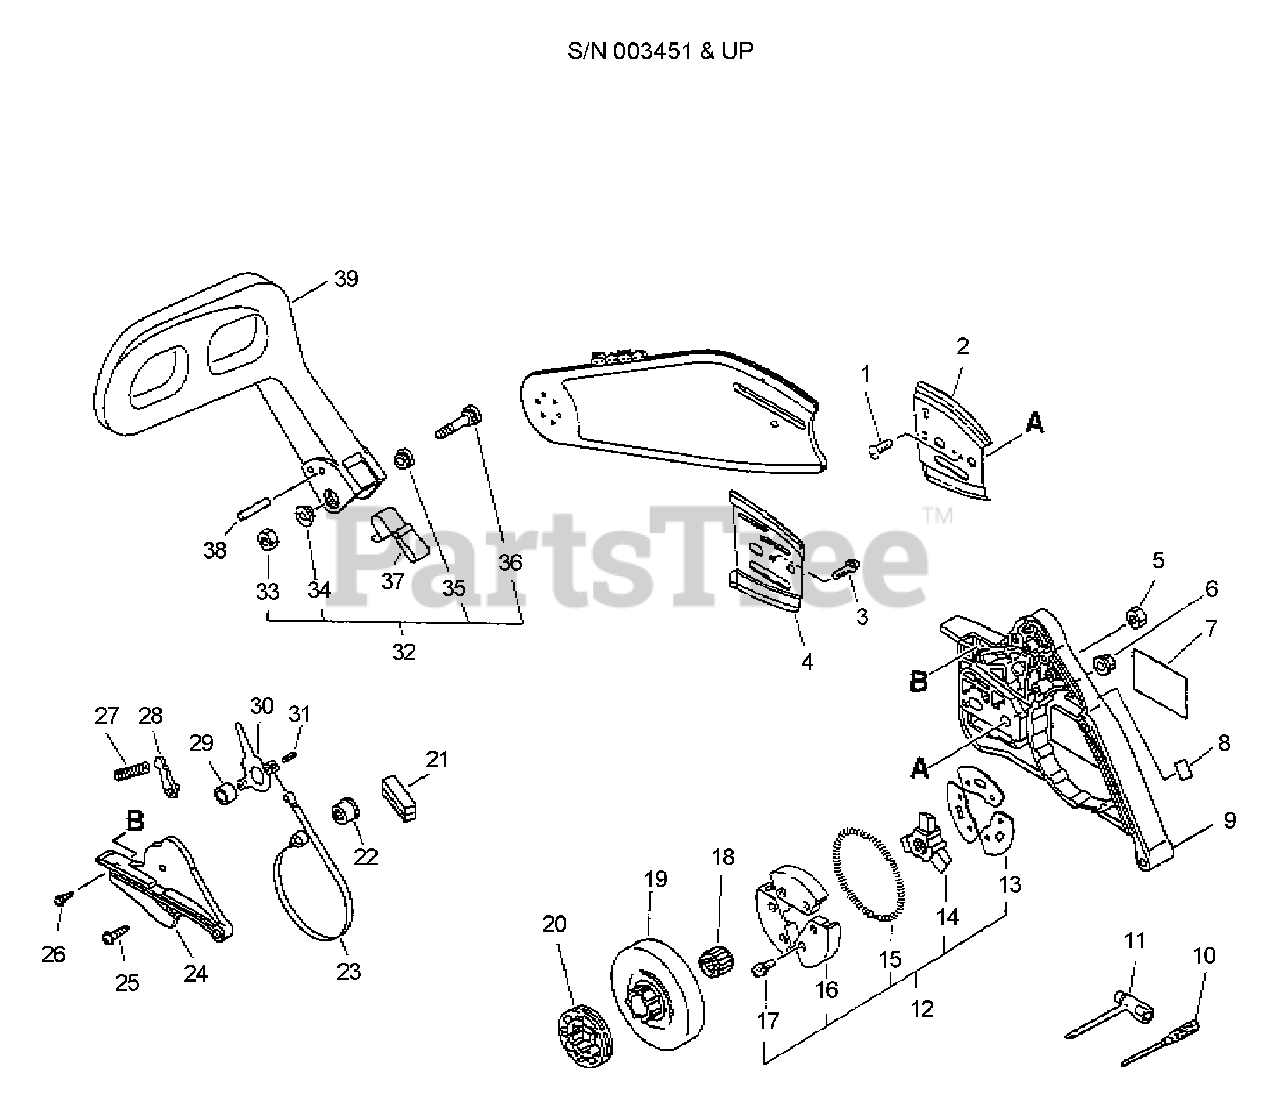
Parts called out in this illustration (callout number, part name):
1	SCREW - 3X6
2	PLATE, GUIDE - OUTER
3	SCREW - 4X8
4	PLATE, GUIDE - INNER
6	NUT - FLANGE
7	LABEL - ECHO
8	LABEL - CAUTION
9	GUARD, SPROCKET
10	SCREWDRIVER
11	T-WRENCH - 13X19mm
12	CLUTCH ASSY
13	PLATE, CLUTCH
14	HUB, CLUTCH
15	SPRING, CLUTCH
16	CLUTCH SHOE SET
17	SCREW - 4X6
18	BEARING, NEEDLE
19	DRUM, CLUTCH
20	SPROCKET, RIM
22	ADJUSTER, BRAKE BAND
23	BAND, BRAKE
24	COVER, BRAKE
25	SCREW - 3X18
26	SCREW - 4X12
27	SPRING, BRAKE
28	STOPPER, BRAKE
29	SPACER - 8
30	LEVER, BRAKE
31	PIN - SPRING -- 4X8
32	MOUNTING KIT
33	LOCKNUT - 5
35	COLLAR - 5
36	SCREW - 5X35
37	SPRING, RETURN
38	PIN - 3.5X26
39	LEVER, BRAKE
